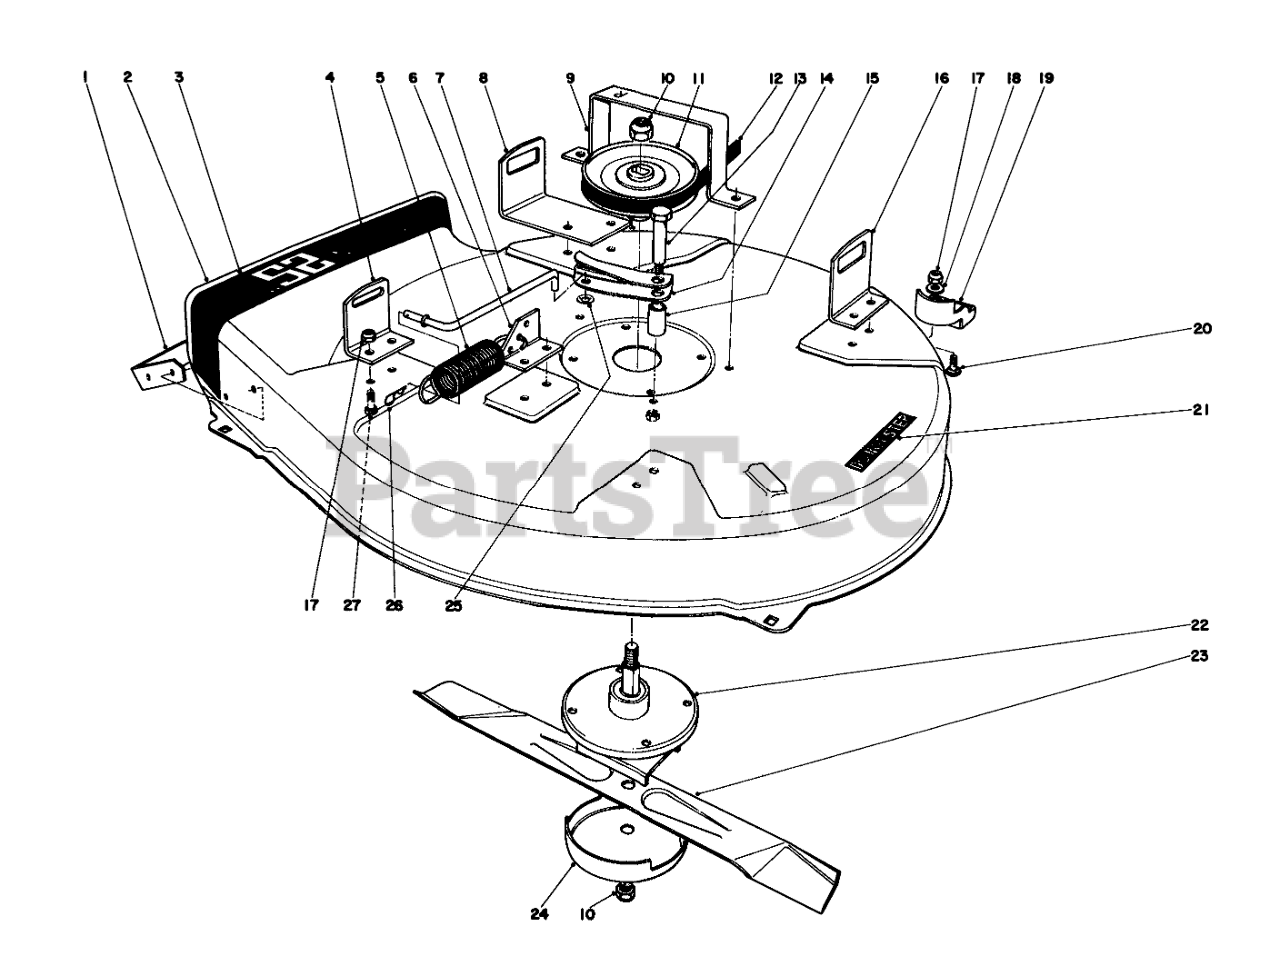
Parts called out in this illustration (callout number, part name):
1	Deflector Bar
2	25" Deck
3	Chute Deflector Decal
4	Front Deck Bracket
5	Spring
6	Deck Spring Bracket
7	Blade Brake Rod
8	Mower Deck Bracket (R. Rear)
9	Belt Guide
11	Pulley
12	V-BELT, DECK DRIVE
13	BOLT-SHOULDER, HH
14	Blade Brake Arm
15	Spacer
16	Mower Deck Bracket (L. Rear)
17	NUT-LOCK, CONE
18	WASHER-PLAIN
20	SCREW-CARR
21	Decal
22	Mower Spindle
23	Blade
24	Cup
25	216 Washer
26	PIN-COTTER
27	SCREW-HH
